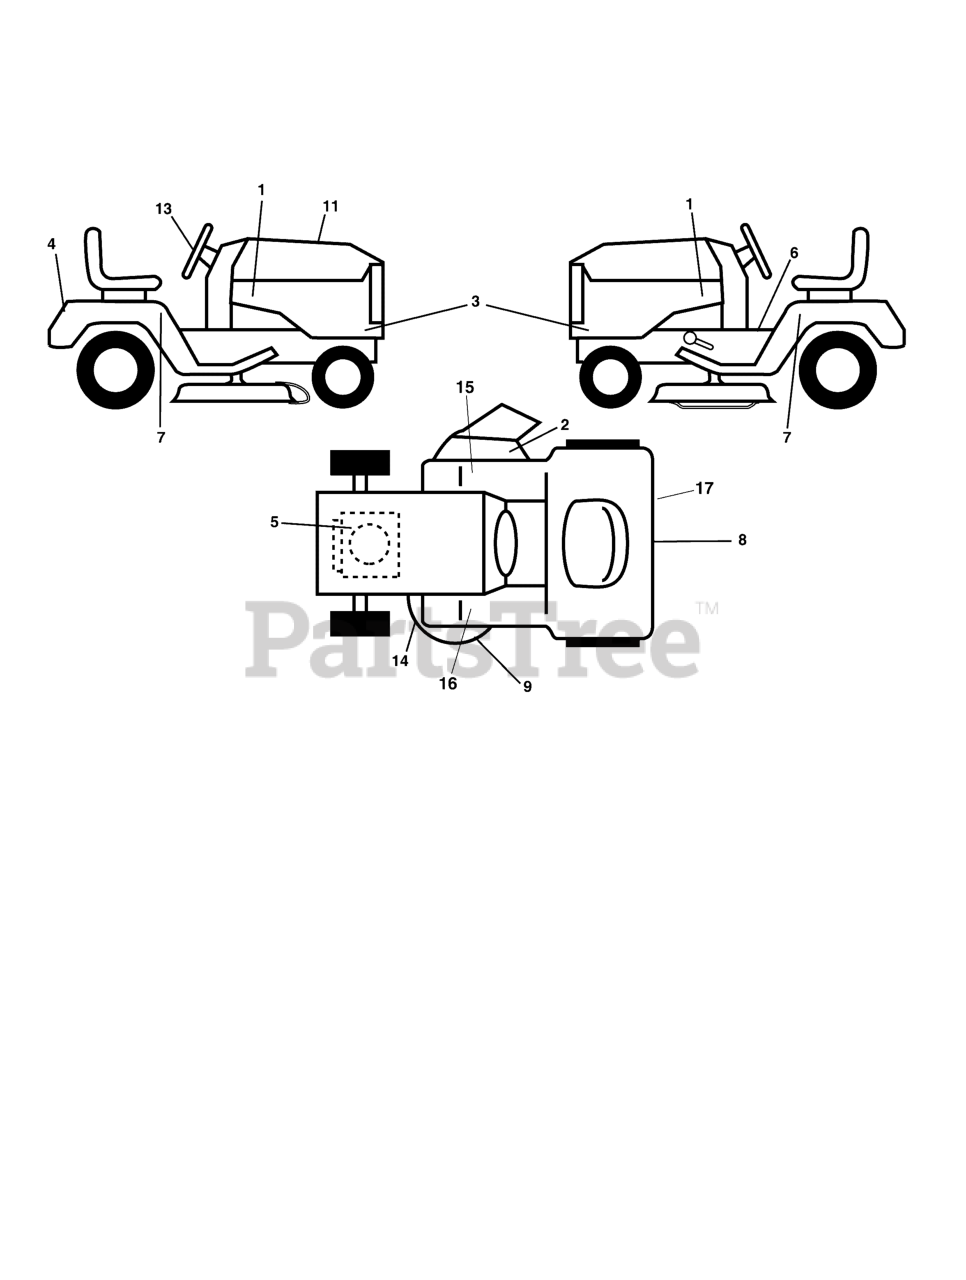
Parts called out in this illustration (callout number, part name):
1	Decal, Hood RH/LH
2	DECAL, Keep Hand Away
3	DECAL, Side Panel
4	DECAL, Fender
5	DECAL, Engine H.P.
6	Decal, Fender Operator's
7	DECAL, Fender LH/RH
8	DECAL, UPD Barcode
9	DECAL, 46" Deck
13	Decal, Steering Wheel
14	Decal, Mower Schematic
15	Pad, Footrest RH
16	Pad, Footrest, LH
17	Decal, Bypass
